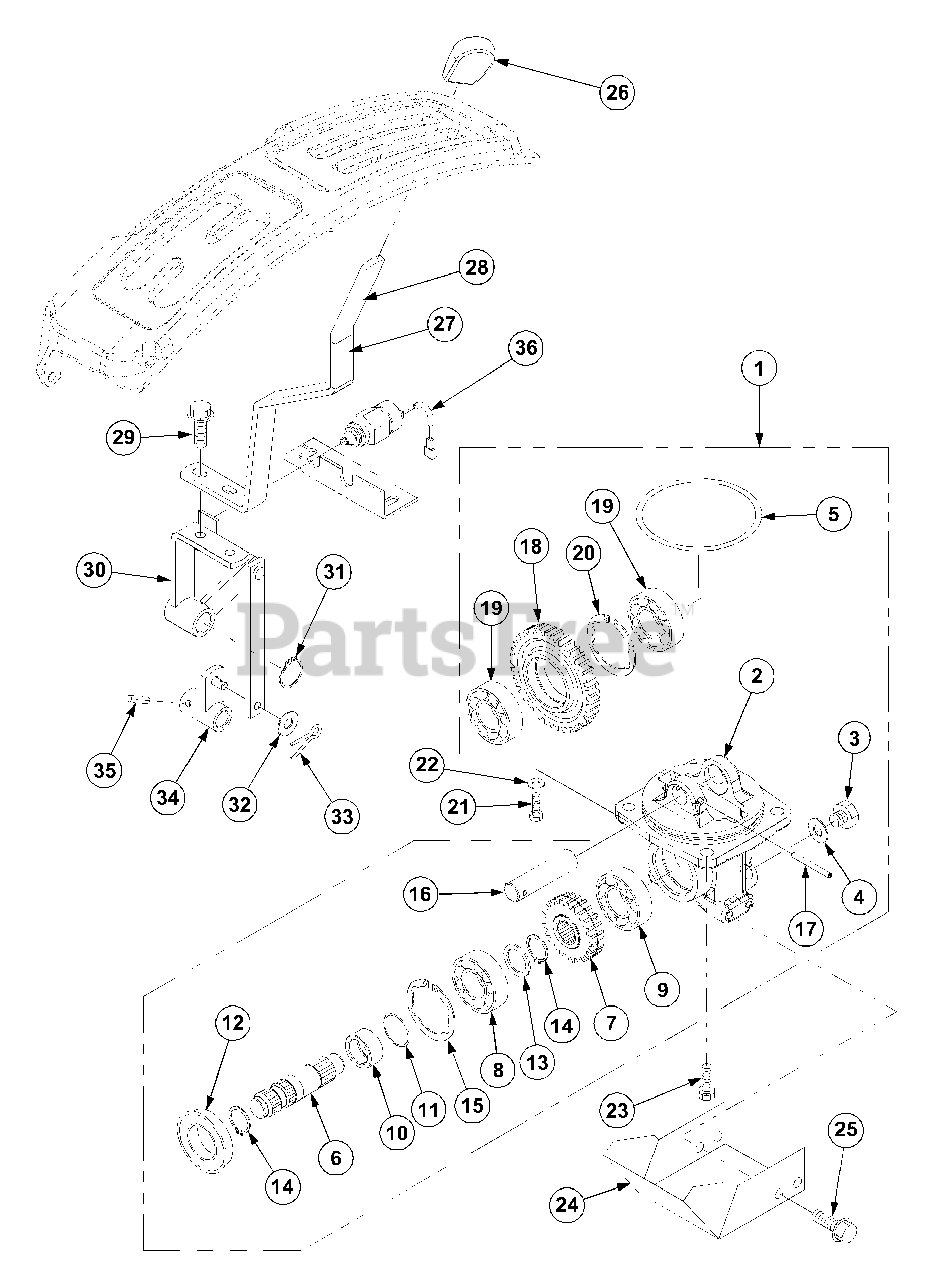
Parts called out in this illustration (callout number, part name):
1	Mid PTO Assy
14	C-Ring
15	C-Ring
20	C-Ring
22	Washer,Spring
23	Bolt,w/Washer
25	Bolt,w/Washer
28	Lever,Mid PTO
29	Bolt,w/Washer
36	Switch,Safety
